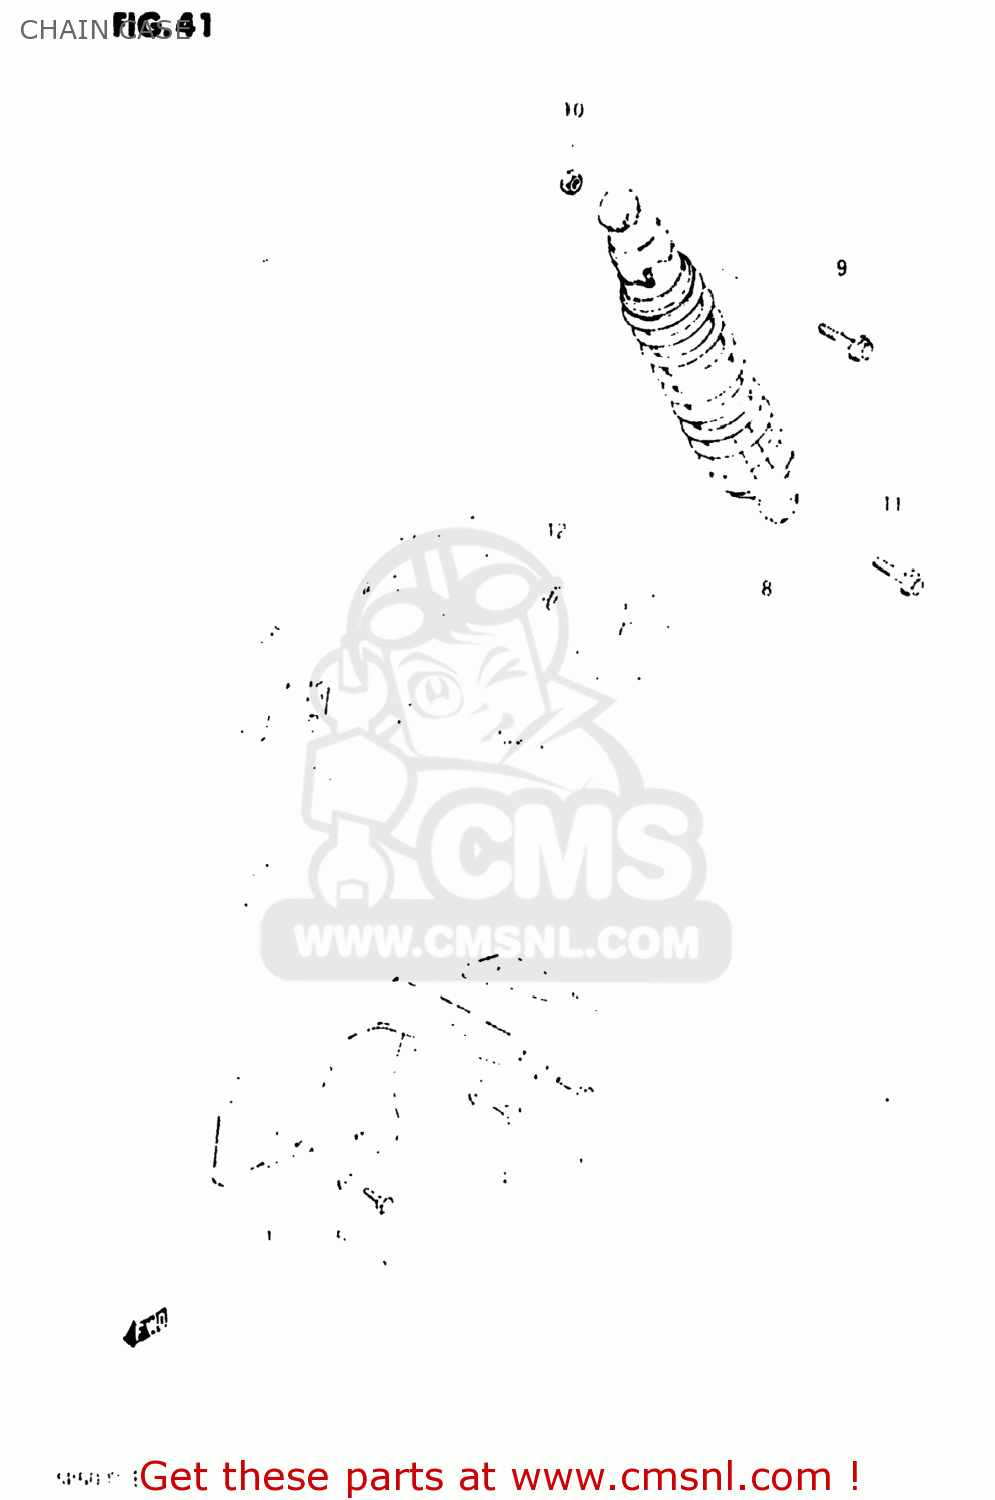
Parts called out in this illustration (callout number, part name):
1	CASE,CHAIN
2	REINFORCEMENT,CHAIN CASE
3	BOLT
4	BOLT 6X8
5	WASHER,LOCK
6	BOLT
7	WASHER
8	ABSORBER ASSEMBLY,REAR SHOCK
9	BOLT(10X40)
10	NUT
11	BOLT(10X50)
12	NUT
